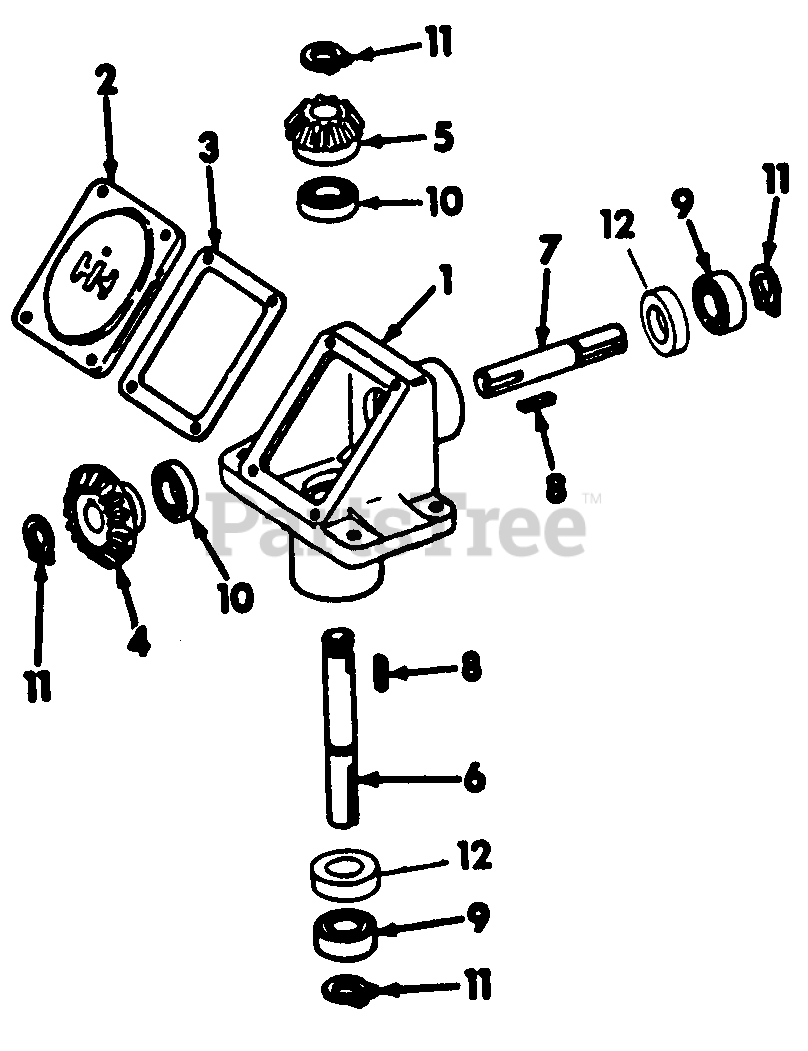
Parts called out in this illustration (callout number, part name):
2	Cover, Gear Box
3	Gasket, Gear Box Cover
4	Gear, Bevel - 30 Tooth
5	Gear, Bevel - 20 Tooth
6	Shaft, Input
7	Shaft, Output
8	Key, 3/16 X 11/16 Sq Parallel
9	Bearing, Ball
10	Bearing, Ball
11	Ring, Retaining
